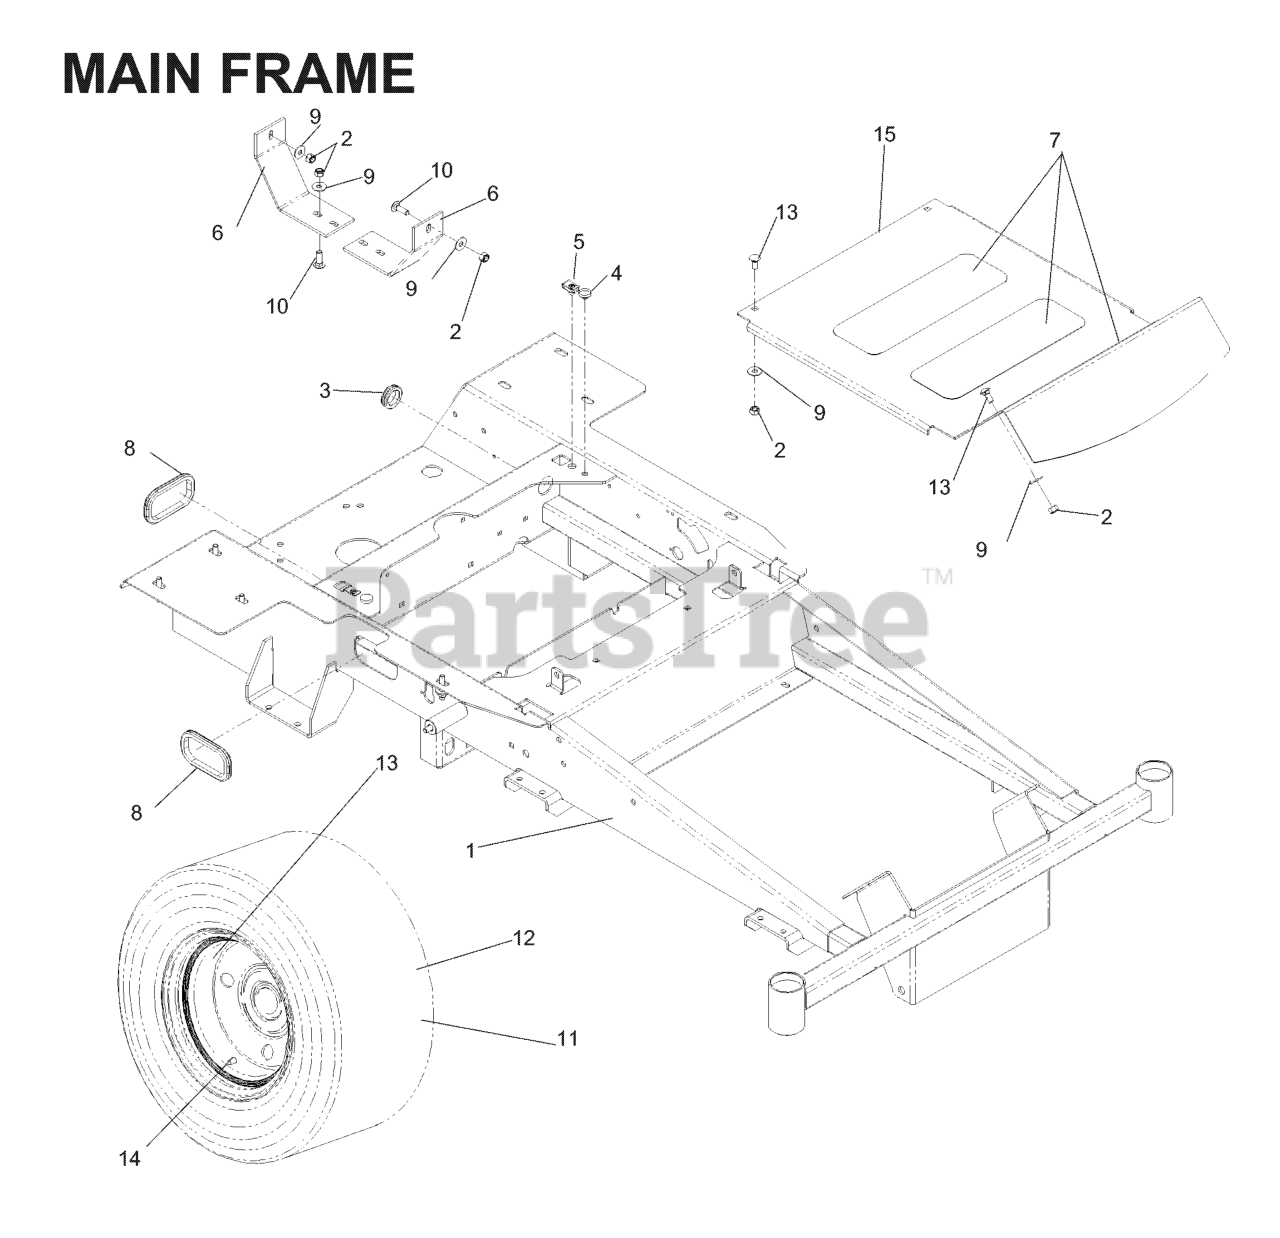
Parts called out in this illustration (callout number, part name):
1	FRAME W/DECALS #
2	NUT 5/16 NYLOC
3	RUBBER GROMMET
4	GROMMET, BUMPER
5	U-CLIP 5/16-18 NUT RETAINER
6	SKID PLATE
7	ANTI-SKID PAD
9	WASHER 5/16 FLAT
10	RHSNB 5/16C X 1
11	TIRE ASM 18 X 8.5-8
12	TIRE 18 X 9.5 TURF RIDER
13	RIM.8X7.W/8".OFFSET.SILVER.ZTR
14	VALVE STEM TR-412
